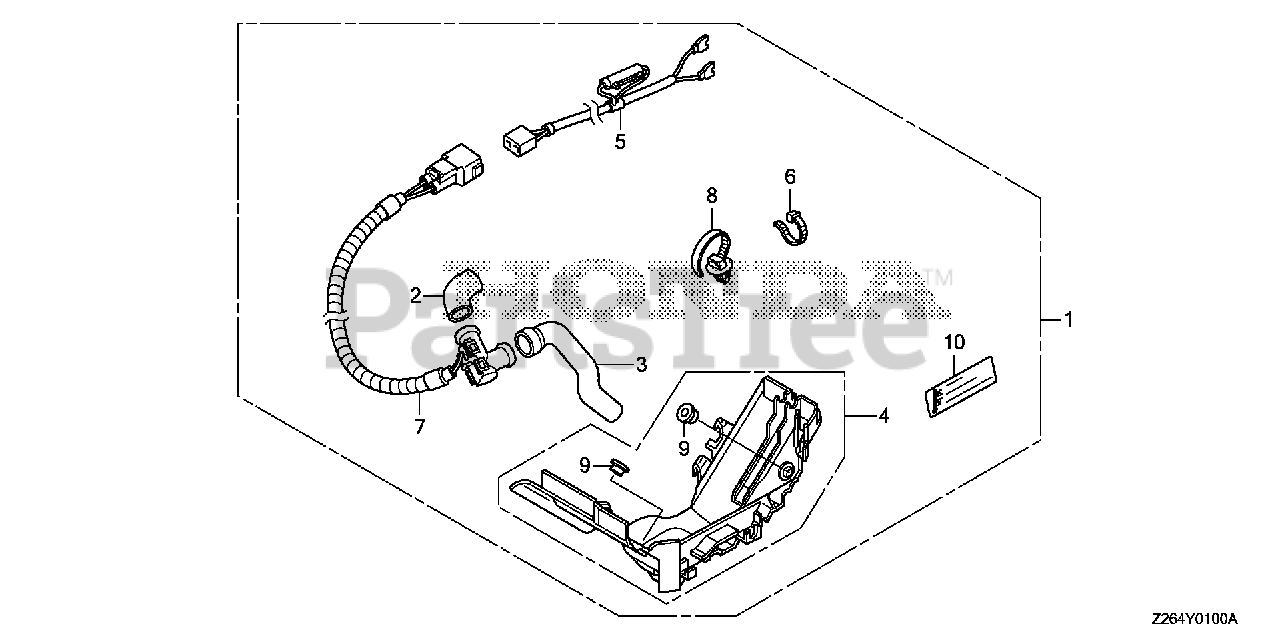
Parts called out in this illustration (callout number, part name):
1	HEATER KIT, BREATHER
2	TUBE, BREATHER
3	TUBE B, BREATHER
4	SHROUD (UPPER)
5	SUB-WIRE ASSY.
6	TIE, CABLE (C)
7	HEATER ASSY., BREATHER (L)
8	CLIP, HARNESS BAND (151.5MM) (NATURAL)
9	COLLAR, FAN COVER
10	MARK (CCT)
